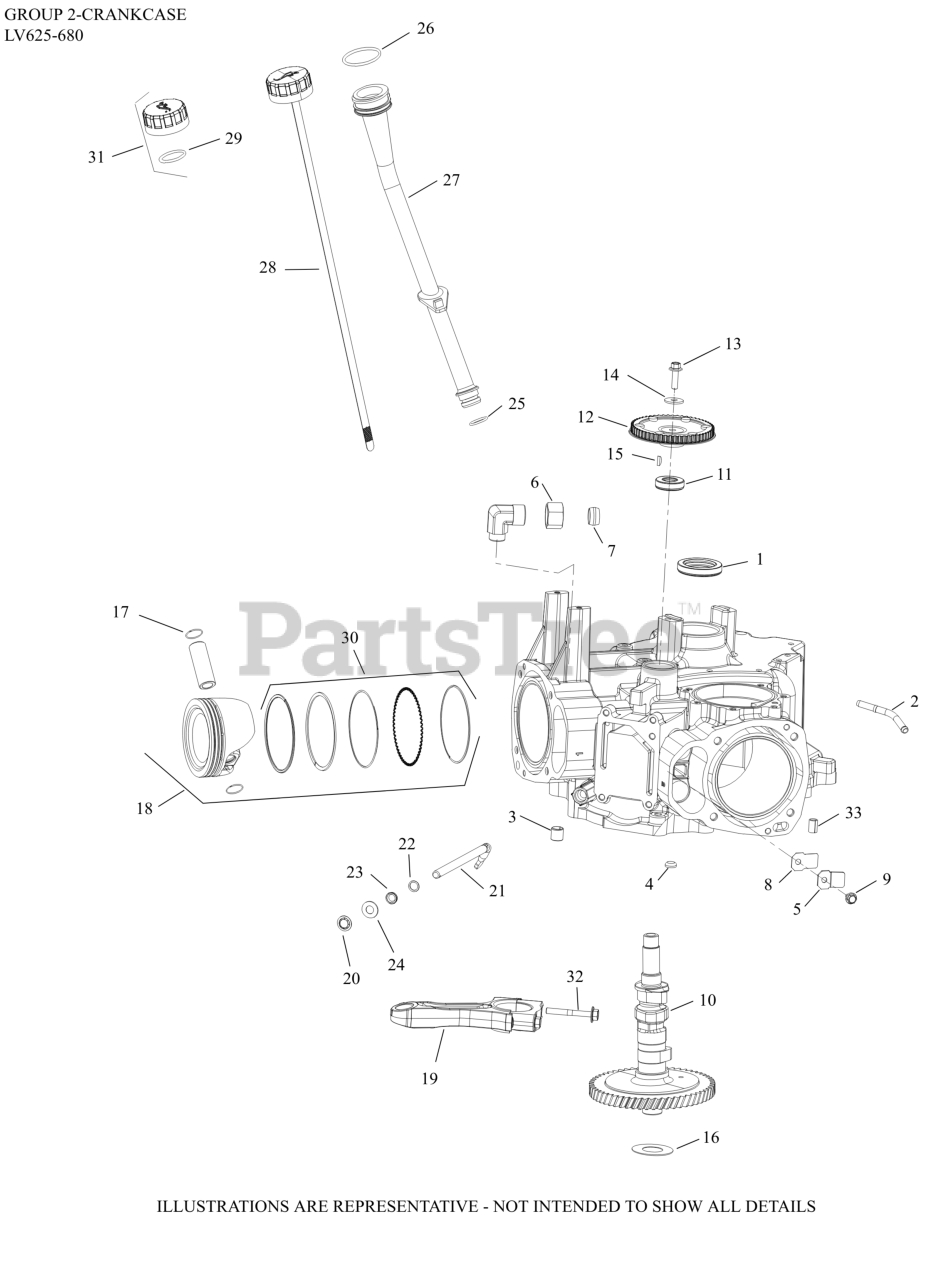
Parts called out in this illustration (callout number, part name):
1	SEAL, OIL (HELIX LIP)
3	PIN, LOCATING
4	PLUG, CUP
5	RETAINER, REED - DISCONTINUED
8	REED, BREATHER
9	SCREW, FLG THD FRM M5X.8X10
10	KIT, CAMSHAFT
11	SEAL, CAMSHAFT
12	SPROCKET, CAMSHAFT
13	SCREW, FLG M6x1.0x20
14	WASHER, FLAT 1/4"
15	KEY, 3/32" X 3/8"
16	SHIM, CAMSHAFT (WHITE .028")
16	SHIM, CAMSHAFT (BLUE .03")
16	SHIM, CAMSHAFT (RED .032")
16	SHIM, CAMSHAFT (YELLOW .034")
16	SHIM, CAMSHAFT (GREEN .036")
16	SHIM, CAMSHAFT (GRAY .038")
16	SHIM, CAMSHAFT (BLACK .04")
17	RETAINER, PISTON PIN
18	PISTN W/RING ASSY USE 24 874 46-S
18	KIT, PISTON-USE 24 874 47-S
19	ROD, CONNECTING ASSEMBLY-USE 24 067 28-S
20	RETAINER, RING
21	SHAFT, GOVERNOR CROSS
22	WASHER, FLAT 11/32"
23	SEAL, GOVERNOR CROSS SHAFT
24	WASHER, FLAT 9 MM
25	O-RING, LOWER OIL FILL TUBE
26	O-RING, UPPER OIL FILL TUBE
27	TUBE, OIL FILL
28	DIPSTICK ASSEMBLY - (#DISCONTINUED)
29	O-RING, DIPSTICK
